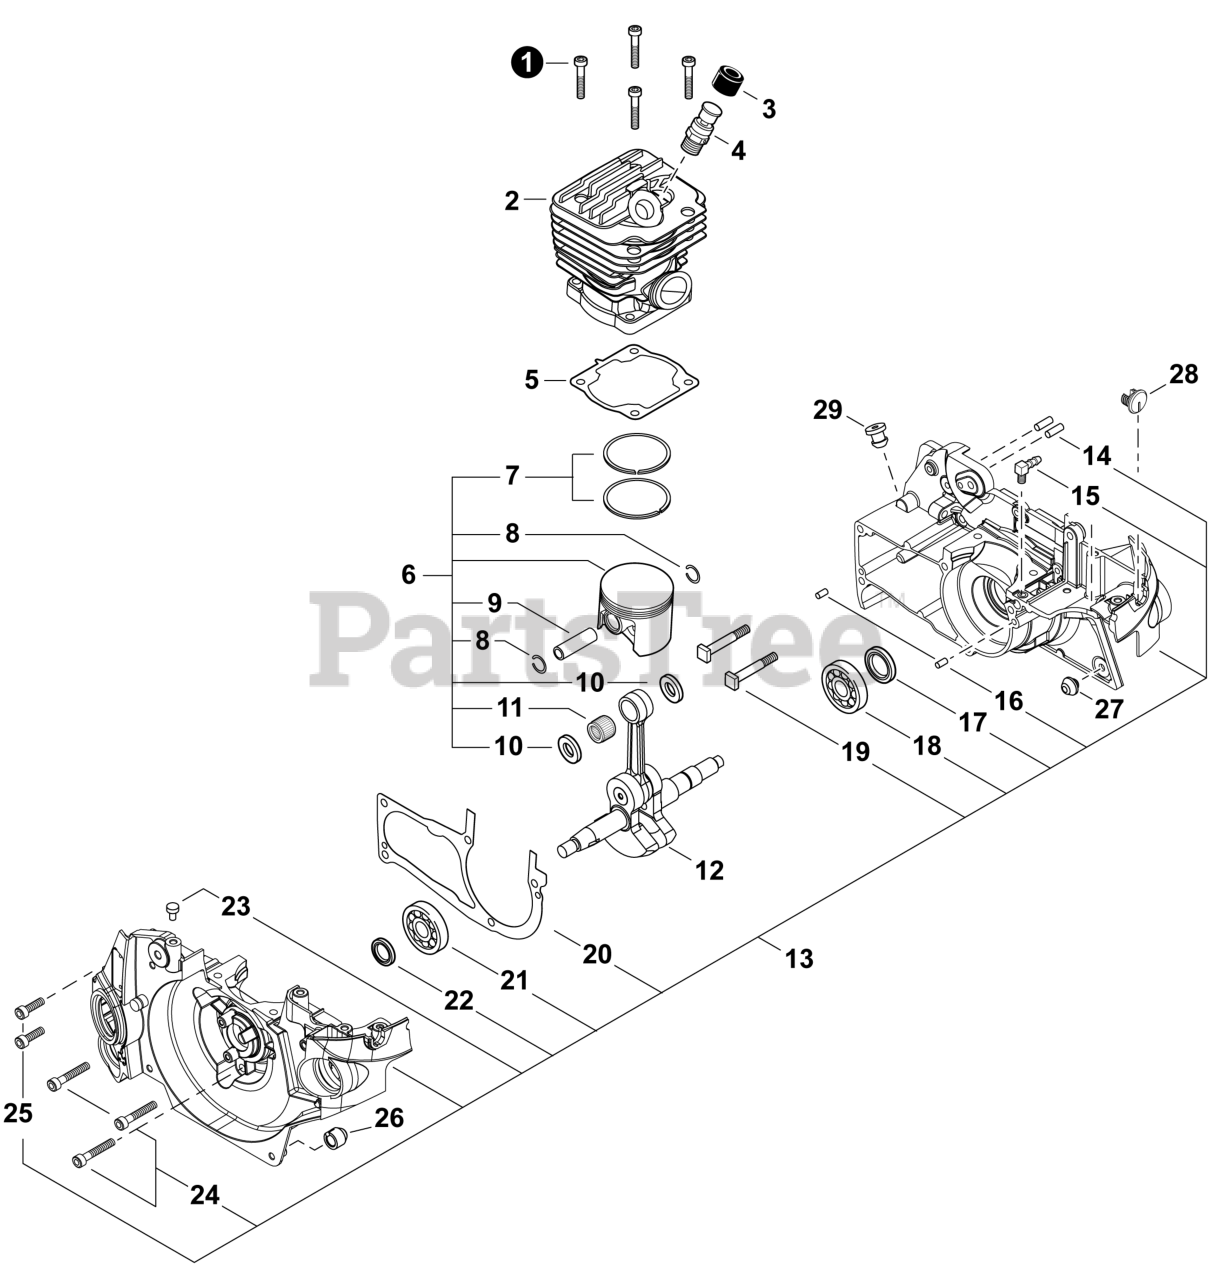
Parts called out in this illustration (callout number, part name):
1	BOLT, ADHESIVE M5×20
2	CYLINDER
3	COVER, DUST
4	VALVE ASSY, DECOMPRESSION
5	GASKET, CYLINDER
6	PISTON KIT
7	RING, PISTON
8	RING, SNAP Ø11
9	PIN, PISTON 11
10	WASHER, THRUST
11	BEARING, NEEDLE 11
12	CRANKSHAFT ASSY
13	CRANKCASE ASSY
14	PIN, LOCATING Ø4×11
15	CONNECTOR, PIPE
16	PIN, LOCATING 4×8
17	SEAL, OIL 15
18	BEARING, BALL 6202 C3
19	BOLT, STUD 8
20	GASKET, CRANKCASE
21	BEARING, BALL 6201
22	SEAL, OIL 12
23	VENT ASSY
24	BOLT M5×35
25	BOLT M5×18
26	CUSHION M
27	CUSHION
29	GROMMET
